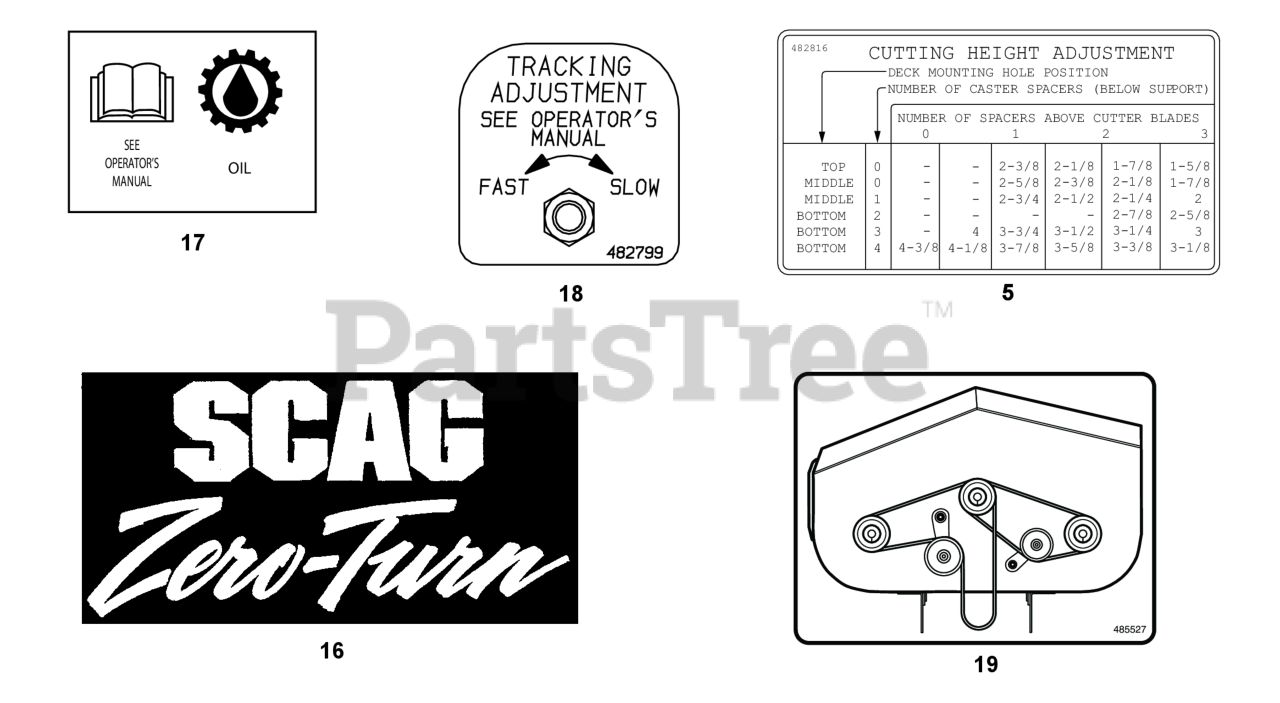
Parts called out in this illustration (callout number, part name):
5	DECAL, HEIGHT OF CUT - SWM
16	DECAL, SCAG ZERO-TURN
17	Decal, Operator's Manual
18	DECAL, TRACKING ADJUSTMENT
19	Decal, Belt Routing - 48V, 52V & 61V
